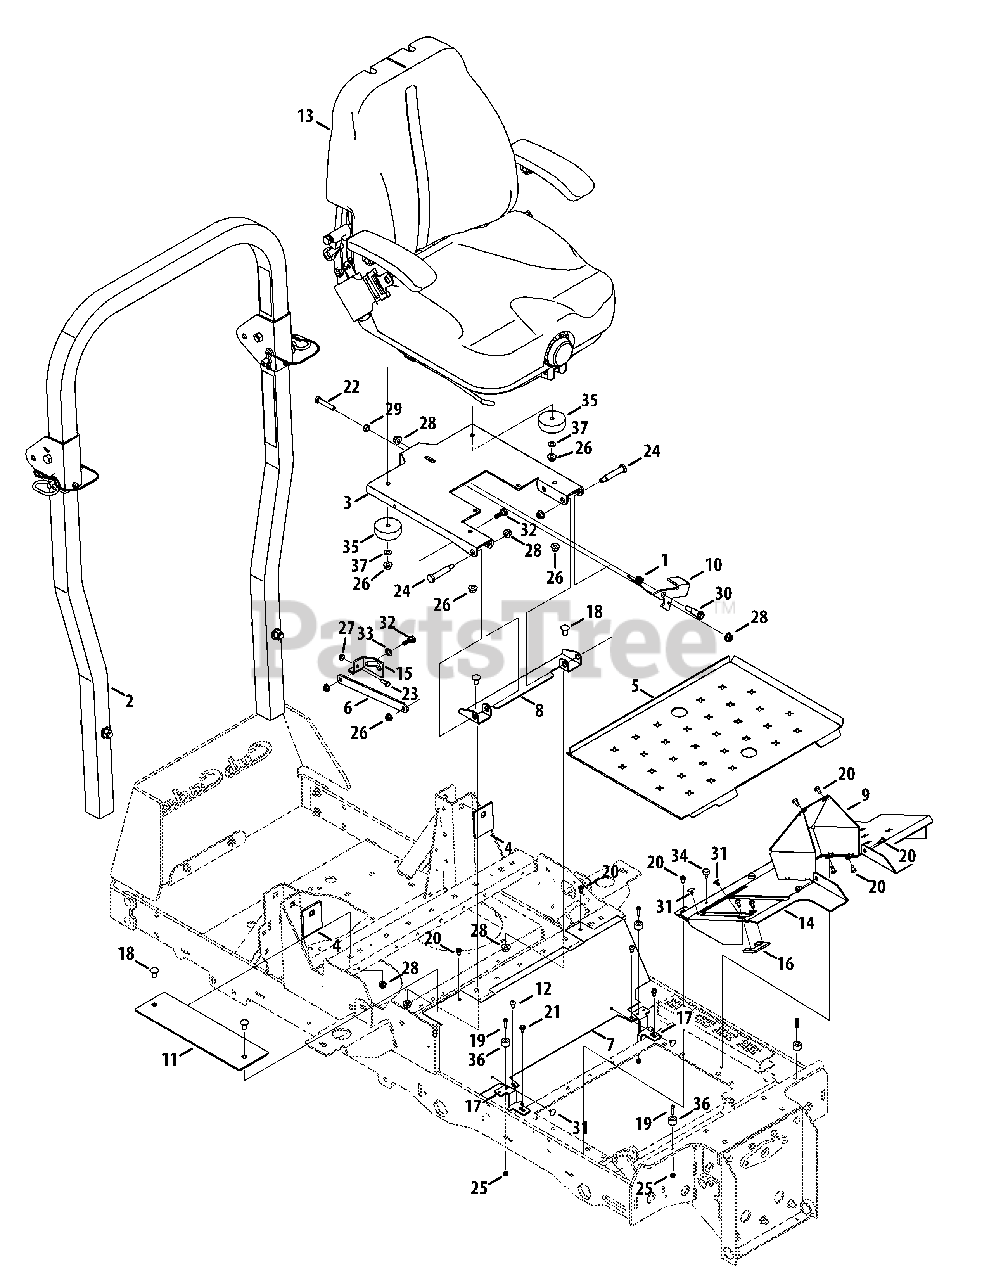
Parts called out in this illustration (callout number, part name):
1	Torsion Spring, .725 x 1.0 x .09
2	Folding ROPS Assembly
3	Seat Mounting Bracket
4	Deck Reinforcement Plate
6	Seat Lockout Bracket
7	Floor Panel Tray
8	Seat Mounting Bracket
10	Seat Lever Latch
11	Seat Panel Cover, RH
12	Screw 1/4-20 x 3.75
15	Seat Lockout Mount
16	Stop Pedal Bracket
17	Frame Bracket, LH
18	Carriage Bolt, 3/8-16 x .75
19	Socket Head Screw, 10-24 x .75
20	Screw, 1/4-20 x .5
21	Hex Flange Screw, 1/4-20 x .500
22	Hex Cap Screw, 3/8-16 x 2.50
23	Hex Cap Screw, 1/4-20 x .75
24	Shoulder Bolt, .500 x 2.23, 3/8-16
25	Nut, #10-24, Hexlock
26	Nut, 5/16-18, Flangelock
27	Nut, 1/4-20, Flangelock
28	Nut, 3/8-16, Flangelock
29	Nut, 3/8-16, Hex
30	Shoulder Bolt, .50 x .925, 3/8-16
31	Clip, .250 Dia. x .500
32	Shoulder Screw, .437 x .268, 5/16-18
33	Washer, .469 x .750 x .06
34	Bumper, .62 Dia. x .3
35	Rubber Bumper, 2.5 x 1.0
36	Rubber Bumper, .75 x .500
37	Washer, .344 x .688 x .065
